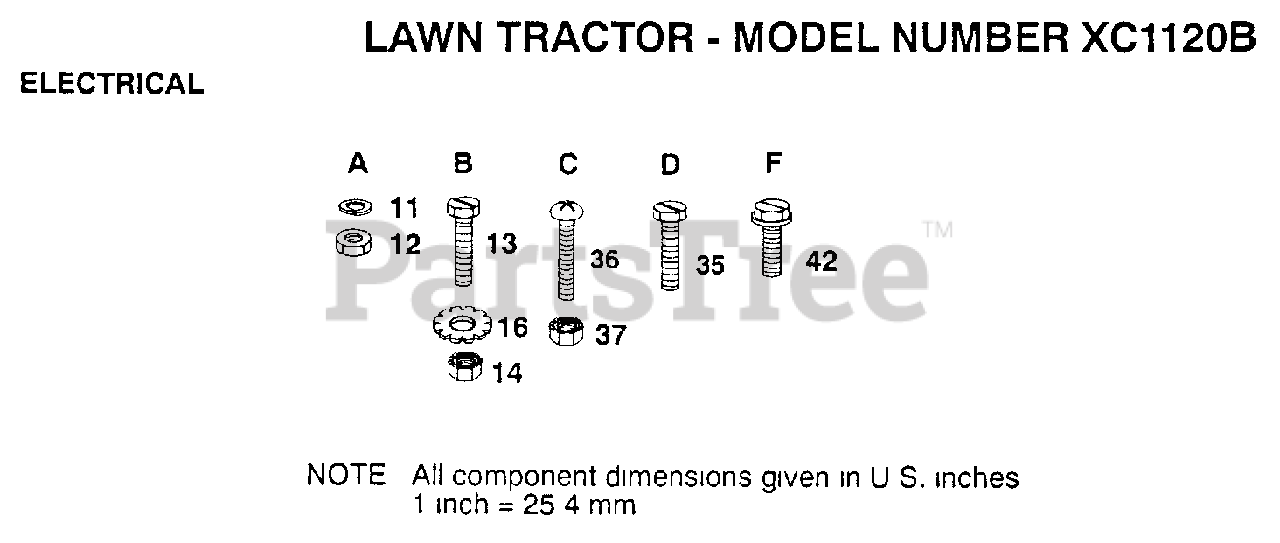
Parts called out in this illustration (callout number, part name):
12	NUT
13	BOLT
14	NUT
35	SCREW
37	"NUT,KEPS"
42	SCREW LT
